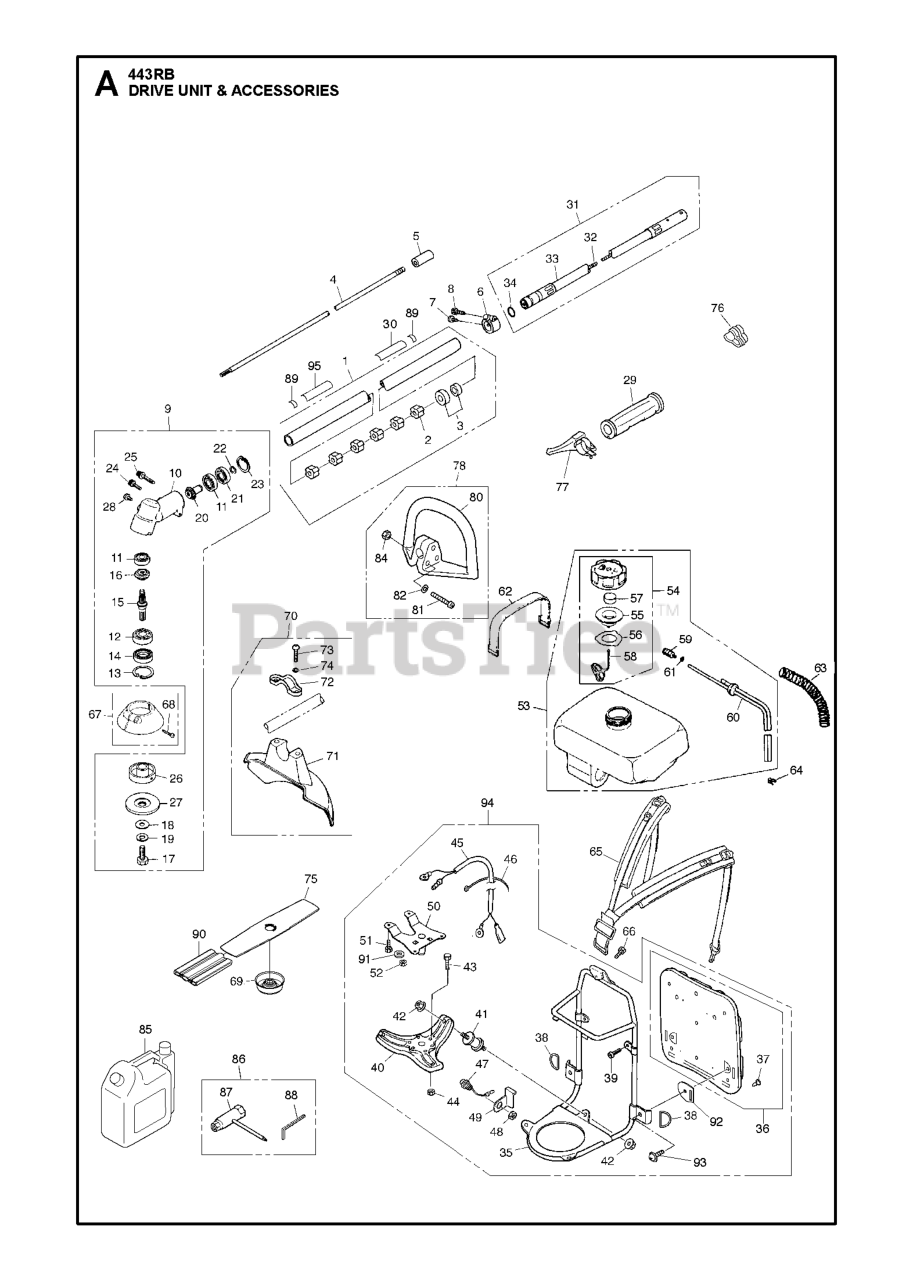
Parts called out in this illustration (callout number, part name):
1	PIPE COMP.(RPLS T321712100)
17	BOLT M8 X L25 L/H
21	BEARING,10MM ID,26MM OD,8MM W
22	RING, SNAP, M10 x 1.0
23	RING,SNAP M26x1.2 RP-318013340
25	BOLT M5 X L10 ALLEN BOLT
27	HOLDER (B)
30	LABEL CAUTION
59	FILTER ASSY
66	BOLT M5 X L10 ALLEN BOLT
67	COVER ASSY
75	GRASS BLADE 1"
81	SCREW 0026000530
